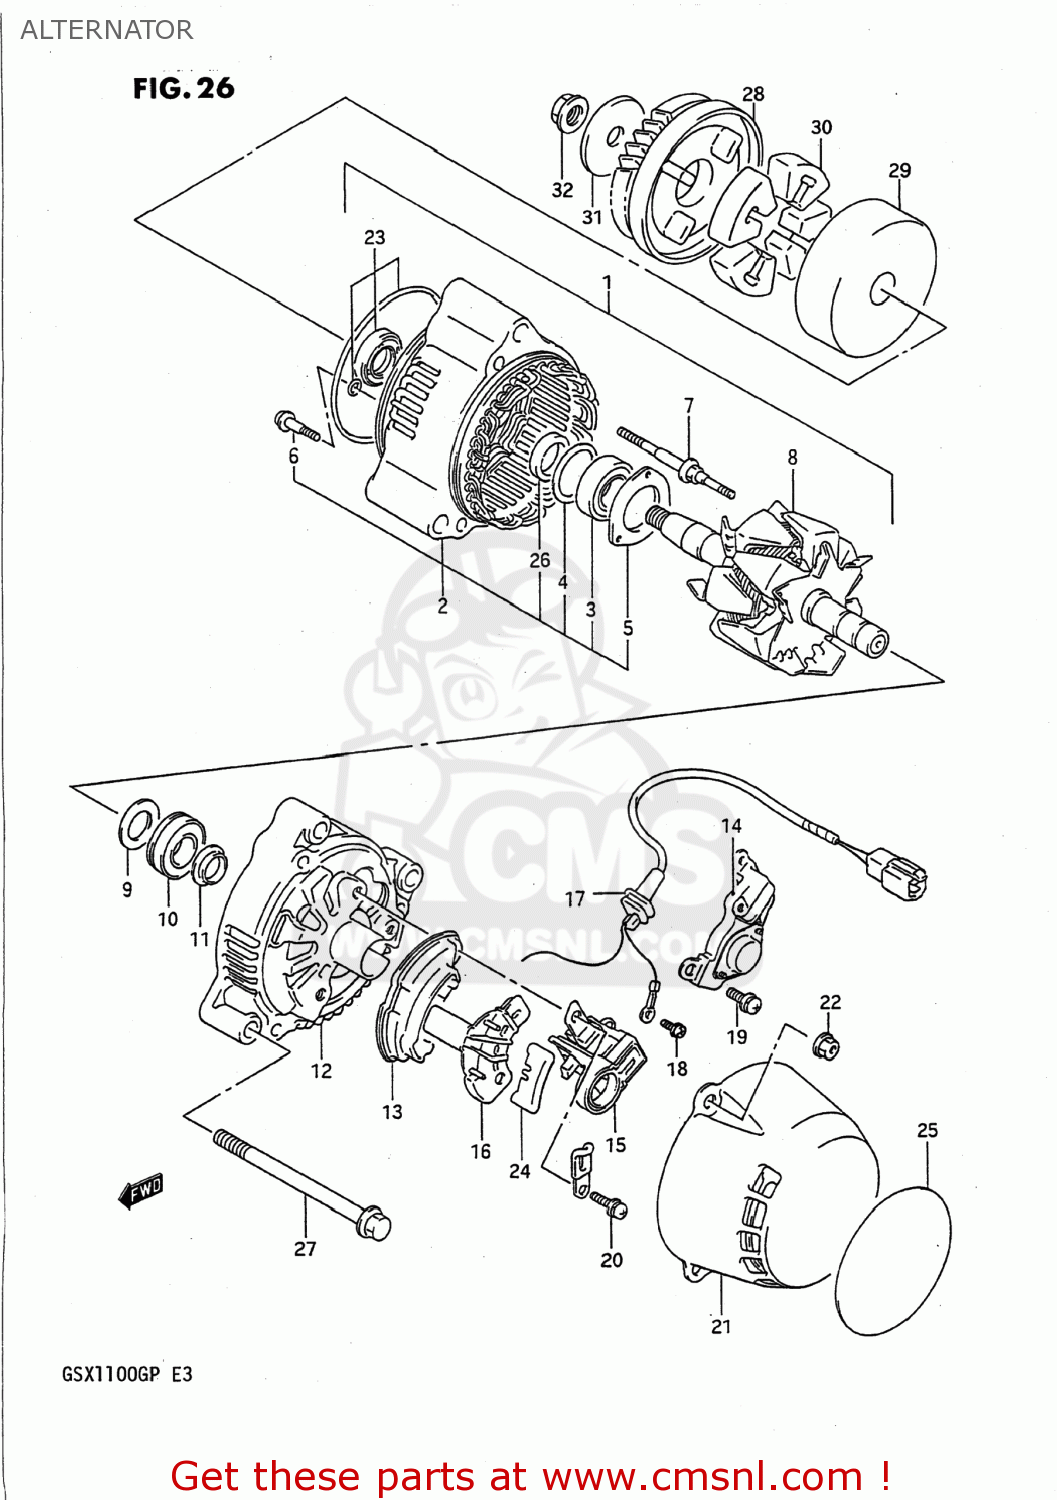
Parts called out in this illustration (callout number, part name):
1	GENERATOR ASSEMBLY
2	FRAME,DRIVE END
3	BEARING
4	COVER,BEARING
5	RETAINER
6	SCREW,BEARING RETAINER
7	STUD BOLT
8	ROTOR ASSEMBLY
9	COVER,BEARING
10	BEARING
11	COVER(2)
12	FRAME,END
13	HOLDER,RECTIFIER
14	REGULATOR
15	HOLDER,BRUSH
16	COVER,RECTIFIER
17	WIRE,LEAD
18	SCREW
19	SCREW
20	SCREW
21	COVER
22	NUT ,5MM
23	SEAL SET,OIL
24	BUSH
25	PROTECTOR,ALTERNATOR
26	SPACER
27	BOLT 8X90
28	GEAR COMP,GENERATOR DRIVE
29	HOUSING,GENERATOR GEAR
30	DAMPER,GENERATOR DRIVE
31	WASHER (10X36X2)
32	NUT
